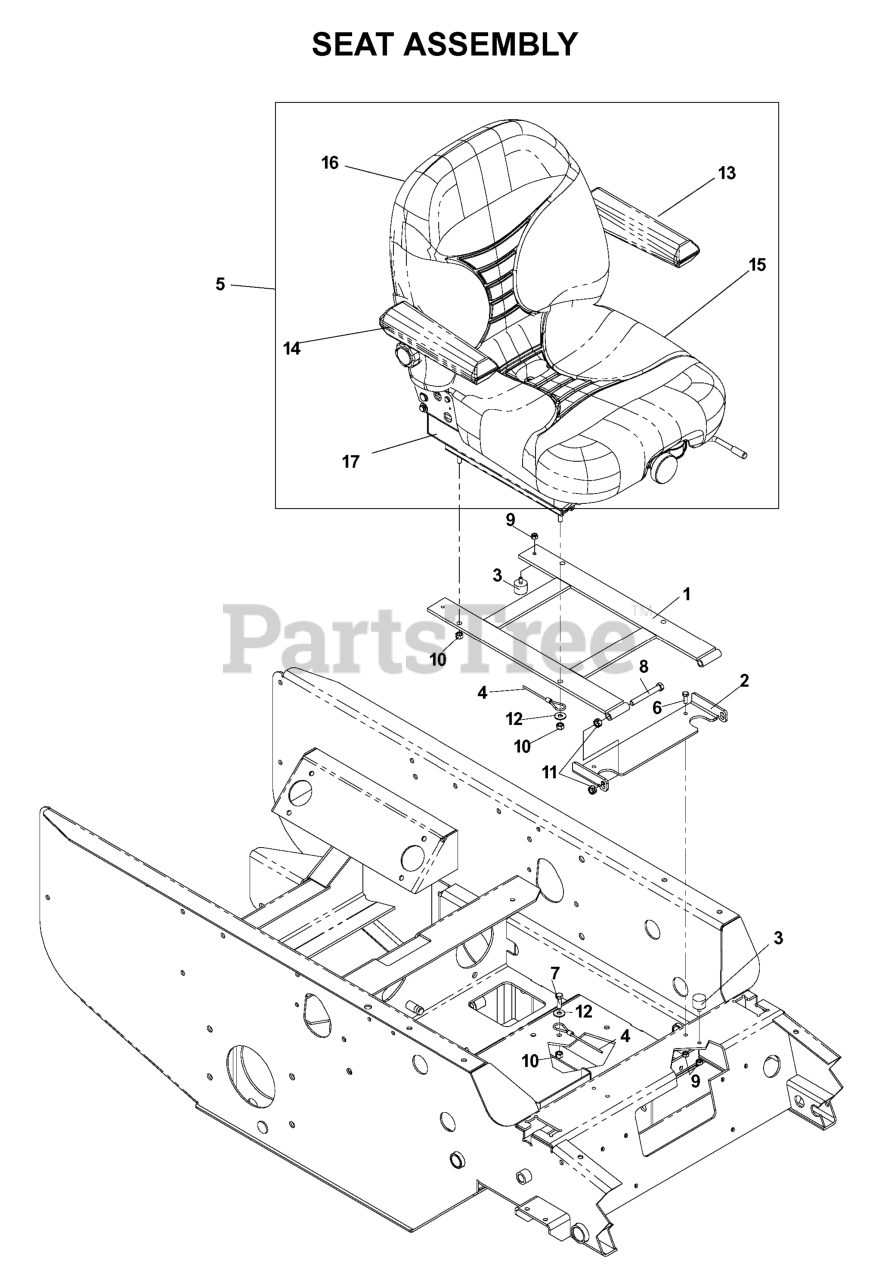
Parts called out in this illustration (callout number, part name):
1	SEAT MOUNT
2	SEAT BKT. W/PAINT
3	STUD/PLATE MOUNT
4	SEAT LANYARD
5	SEAT, SUSPENSION
6	HCS 1/4C X 3/4 HCS
7	HCS 5/16C X 1
8	HCS 3/8C X 3
9	NUT.1/4-20.HEX.NYLOC.ZD
10	NUT 5/16 NYLOC
11	NUT 3/8C CENTERBLOCK
12	WASHER 5/16 FLAT
13	ARMREST KIT, LH
14	ARMREST KIT, RH
15	SEAT CUSHION KIT
16	BACK CUSHION KIT
17	SLIDE KIT, SEAT ADJ
